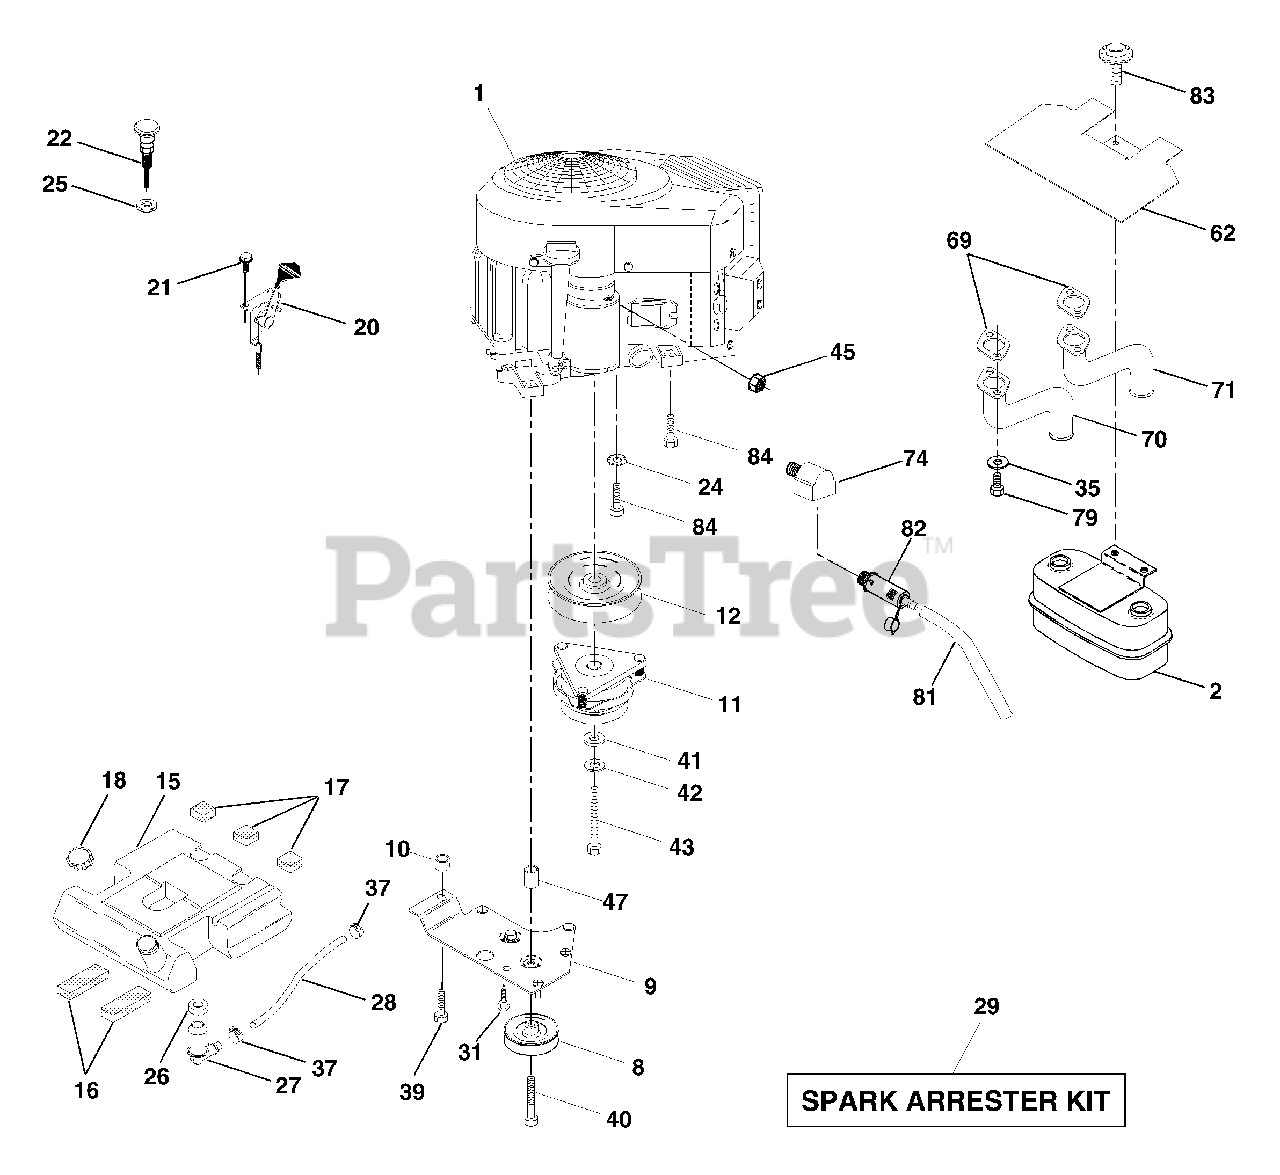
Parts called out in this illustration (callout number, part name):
2	Muffler Side
8	Pulley V-Idler
9	Keeper Asm. Belt Engine VGT
10	Bushing
11	Clutch Electric
12	Pulley Engine VGT Elect Clutch
15	Tank Fuel Rear 3.50
16	Pad Spacer
17	Pad Spacer
18	Top Vented N/LANY
20	Control Throttle
21	Screw Hex Thd Cut 1/4 - 20 X 5/8
22	Control Choke
24	Washer Ext Tooth 3/8
25	Nut Keps 3/8-24 Unf
26	Bushing
27	Stem Tank Fuel
29	Spark Arrester Kit
31	Clip Push-In
35	Washer
37	Clamp Hose
39	Screw TT 3/8-16 x 2-1/4 UNC
40	Screw TT 3/8-16 x 4 UNC
41	Washer 1-1/2 OD X 15/32 ID X .250
42	Washer Lock 7/16
43	Bolt Hex 7/16-20 X 4 Gr. 5
45	Nut Keps Hex 1/4-20
47	Spacer
62	Shield Heat Muffler CV-Intek
69	Gasket
70	Tube Exhaust LH
71	Tube Exhaust RH
74	Elbow Street Brass
79	Screw Hex Hd Cap 5/16-18 x 3/4
81	Tube Drain Oil Easy
82	Plug Oil Drain Easy
83	Bolt 5/16-18unc X 1-3/4 W/Sems
84	Screw Thdrol 3/8-16 x 1-1/2
